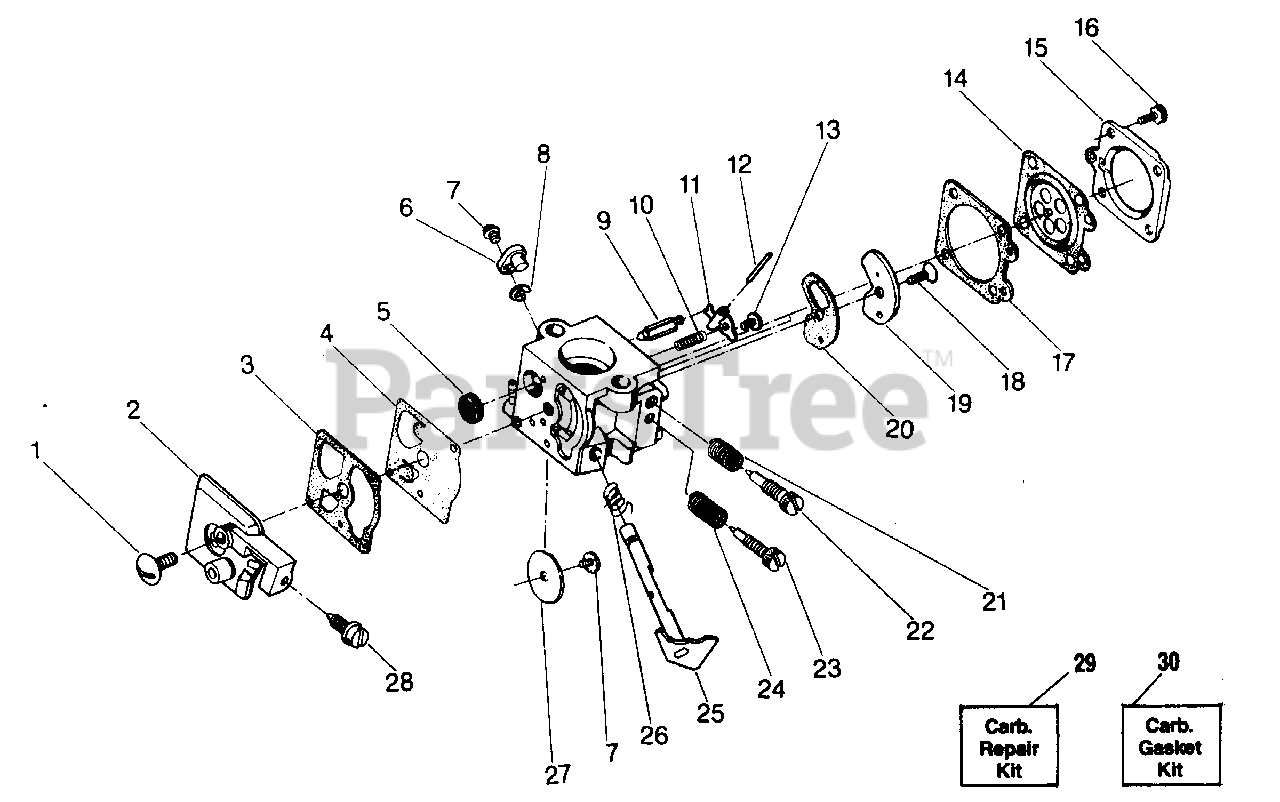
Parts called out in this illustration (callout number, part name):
1	Screw - Pump Cover
2	Pump Cover Ass'y (incl. #28)
3	Gasket - Pump
4	Diaphragm - Pump
5	Screen - Inlet
6	Swivel Lever Ass'y.
7	Screw - Throttle Valve
8	Clip - Throttle Shaft
9	Valve - Inlet Needle
10	Spring - Metering Lever
11	Lever - Metering
12	Pin - Metering Lever
13	Screw - Metering Lever Pin
14	Diaphragm Assembly - Metering
15	Cover - Metering Diaphragm
16	Screw Assembly - Metering Cover & Throttle Shaft Clip
17	Gasket - Metering Diaphragm
18	Screw - Circuit Plate
19	Plate - Circuit
20	Gasket - Circuit Plate
21	Spring - Hi Speed Needle
22	Needle - Hi Speed
23	Needle - Idle
24	Spring - Idle Needle
25	Shaft Assembly - Throttle
26	Spring - Throttle Return
27	Valve - Throttle
28	Screw - Idle Adjustment
29	Kit - Carb. Kwik Repair
30	Kit - Carb. Gasket/Diaphragm
